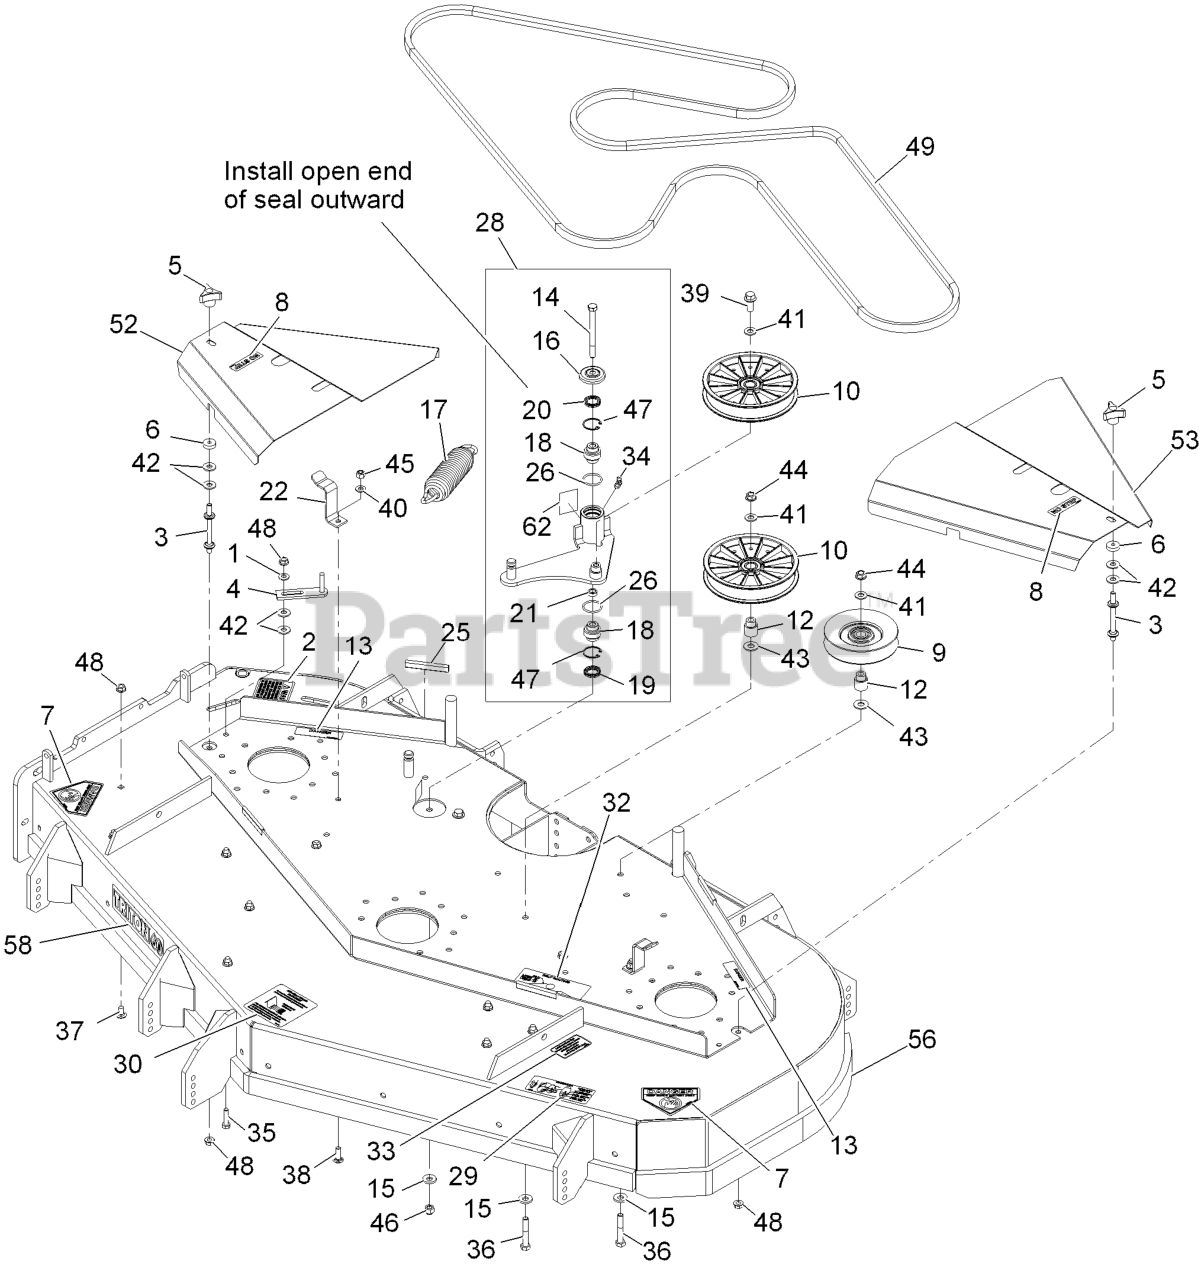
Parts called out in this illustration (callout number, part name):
1	WASHER-SPRING
2	DECAL-WARNING, DISCHARGE
3	STUD-SHIELD, BELT (SHORT)
4	GUIDE-BELT
5	KNOB-3 PRONG
7	DECAL-DANGER
8	DECAL,NO STEP
9	PULLEY-IDLER
10	PULLEY,IDLER 6"
12	BUSHING-IDLER
13	DECAL-COVER, MISSING
14	SCREW-HH
15	WASHER-BELLEVILLE
16	GUARD-TOP
18	BEARING-SPHERICAL
19	SEAL-LIP, DOUBLE
20	SEAL-LIP, SINGLE
22	LATCH,BELT SHIELD
25	STRIP-SEAL
28	KIT, IDLER ARM W/BEARINGS
29	DECAL,BAFFLE ADJUSTMENT
30	DECAL,ANTISCALP
32	DECAL,BELT ROUTING
33	DECAL,BOLT TORQUE
34	FITTING-GREASE, 90 DEG
35	SCREW-HH
36	SCREW-HH
37	SCREW-CARR
38	SCREW-CARR
39	SCREW-HHF
40	WASHER-PLAIN
41	WASHER-FLAT
42	WASHER-FLAT
43	WASHER-FLAT
44	NUT-HHF, WHIZ
45	NUT-LOCK, NI
46	NUT-LOCK, NI
47	RING-SNAP
49	BELT-V
52	SHIELD, BELT RH 725 W/DEC
53	SHIELD,BELT LH 725 W/DECA
56	ASM, DECK 725 W/DECALS
58	DECAL,TRITON 72
62	DECAL,GREASE
